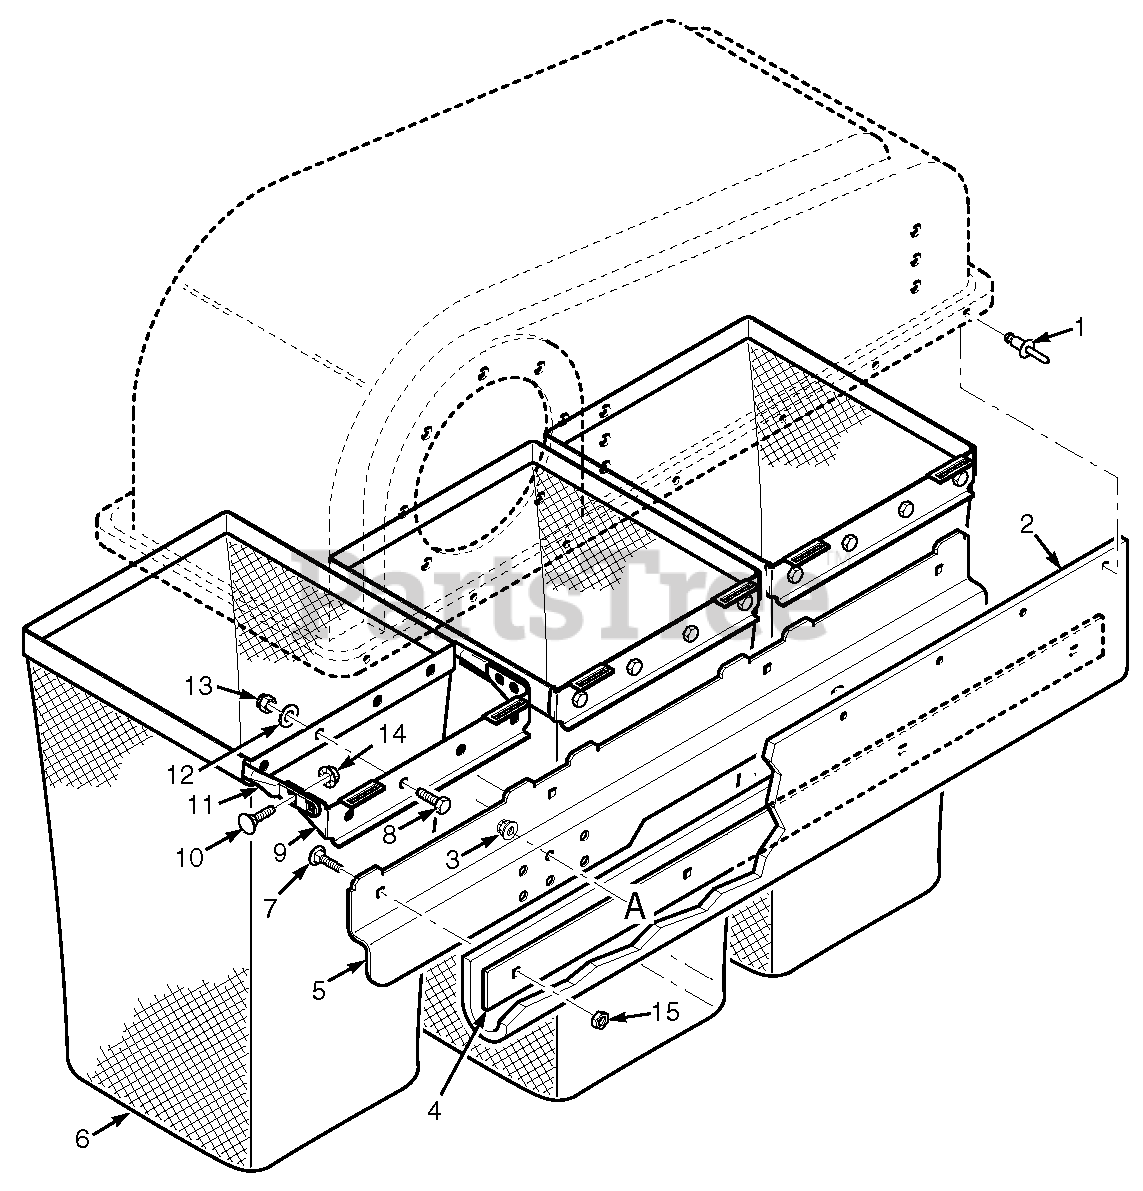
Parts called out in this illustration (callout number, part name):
1	Pop Rivet, 3/16 x .652
2	Seal, Hood
3	Nut, Elastic Flange 3/8-16
4	Retainer, Seal
5	Support, Bag Frame
6	Bag Assembly
7	Bolt, Carriage 1/4-20 x 3/4"
8	Bolt, Hex Head 5/16-18 x 3/4"
9	Mount, Bag Frame Tube
10	Bolt, Carriage 5/16-18 x 3/4"
11	Tube, Bag Support
12	Flatwasher, 5/16-.375 x .875 x .083
13	Nut, Elastic Stop 5/16-18
14	Nut, Serrated Flange 5/16-18
